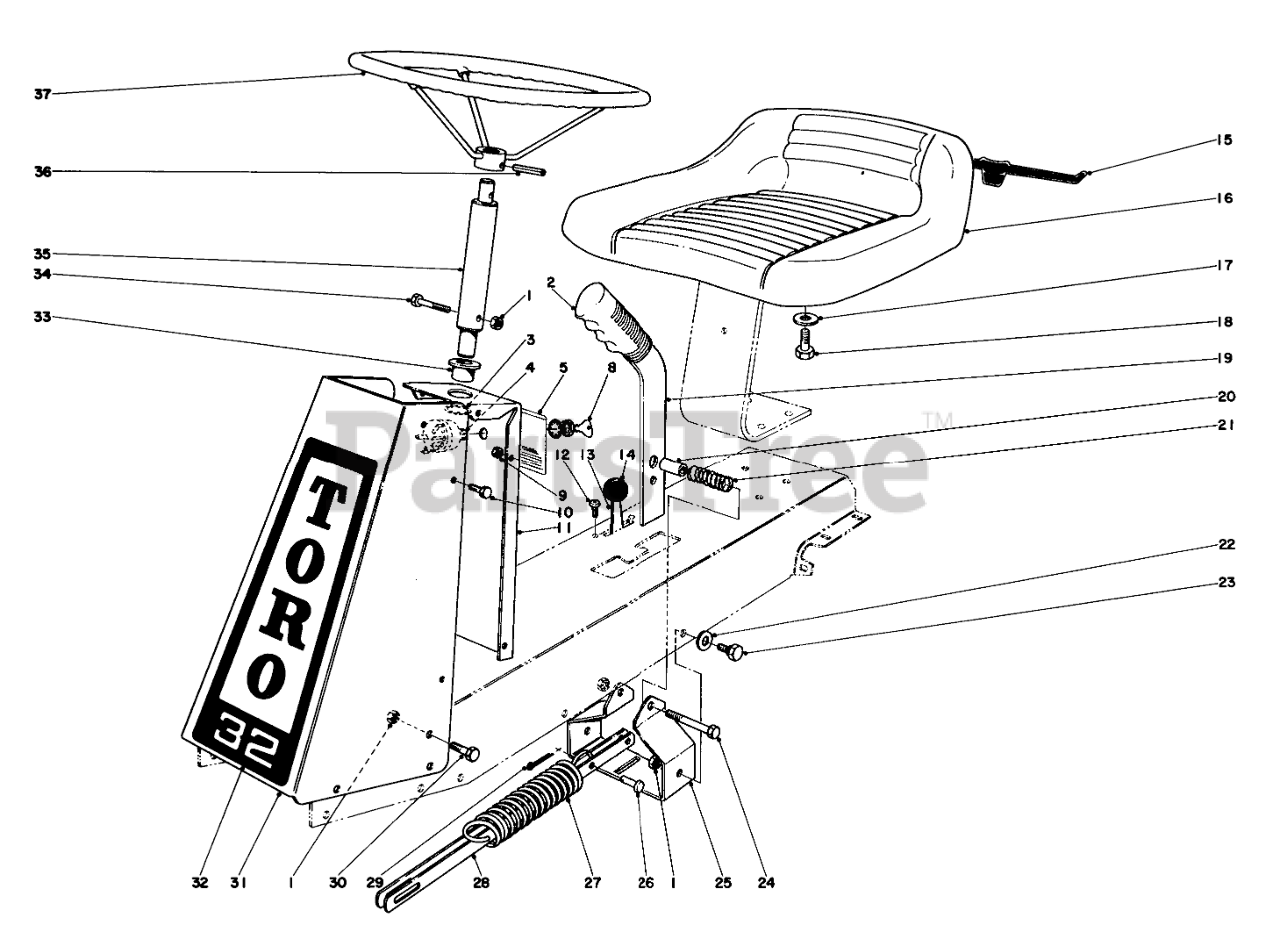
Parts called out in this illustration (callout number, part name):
1	Nut
2	Grip Handle
3	Retaining Ring
4	Switch (Model 56150)
5	Decal Caution (Model 56150)
8	Key
9	NUT-LOCK
10	SCREW-HH
11	Steering Column
12	Screw
13	Throttle Control
14	Knob
15	Decal
17	WASHER-FLAT
18	HEX HD CAPSCREW
19	Handle, Clutch
20	Spacer
21	Spring
22	WASHER-FLAT
23	Screw
24	SCREW-HH
25	Pivot
26	PIN-CLEVIS
27	Spring
28	Clutch Tie Bar
29	PIN-COTTER
30	SCREW-HH
31	Cover, Steering Column
32	Decal
33	Bushing
34	SCREW-HH
35	Steering Shaft
36	PIN-ROLL
37	Steering Wheel
